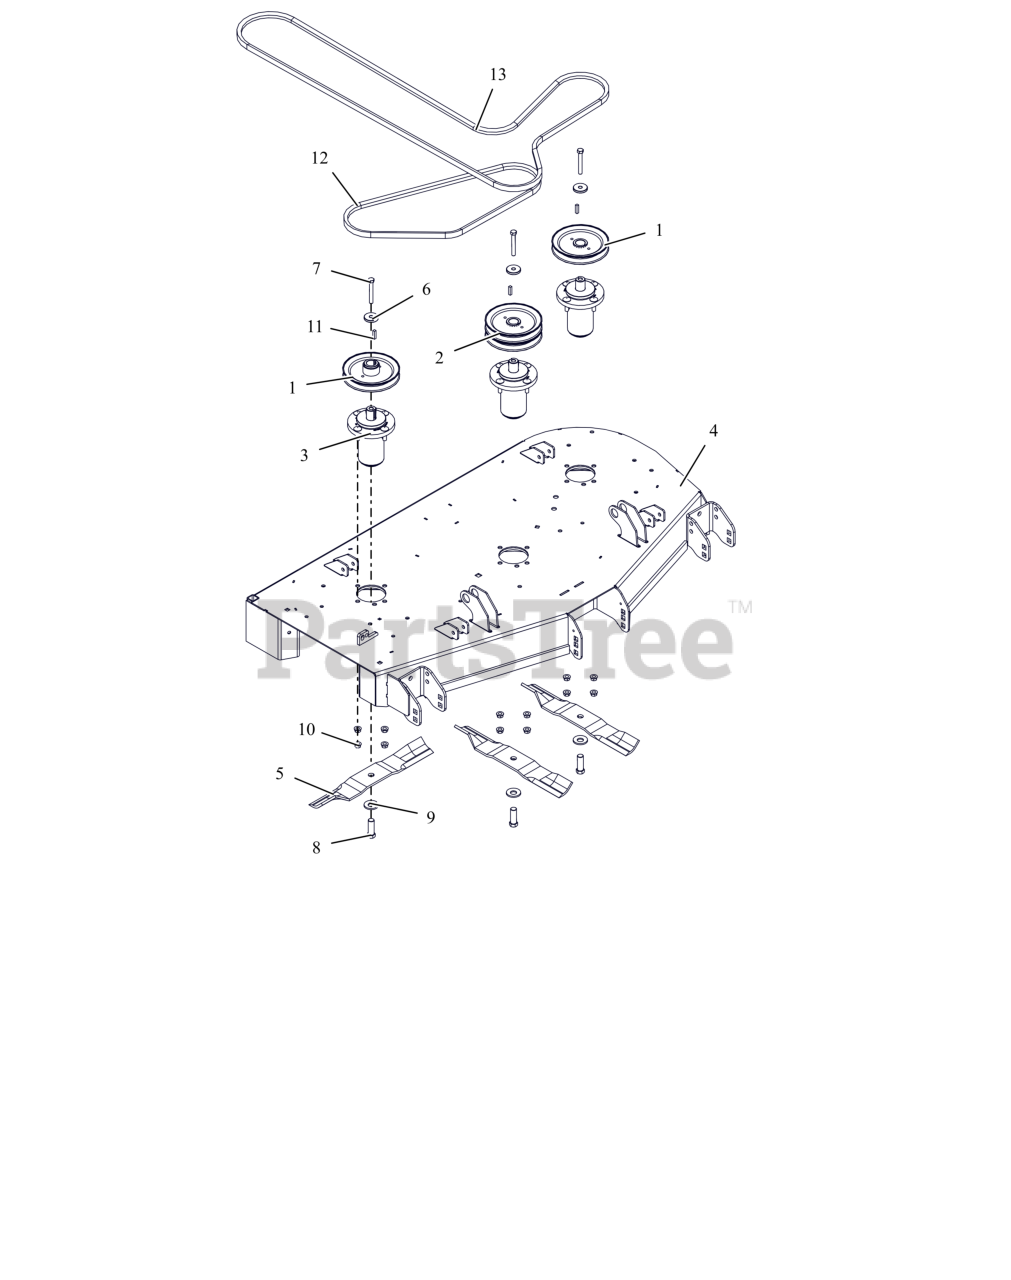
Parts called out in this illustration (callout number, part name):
1	PULLEY, SINGLE-1"ID X 6" OD
2	PULLEY, DOUBLE
3	ASM, MAINT FREE ALUM SPINDLE
4	KIT,DECK-48" W/DECALS-GRAVELY
5	BLADE, 16.19" MOWER (HI-LIFT)
6	RETAINER, SHEAVE
7	BLT, HEX .38-16X2.75 G8 ZCC
8	BLT, HEX .62-18X1.75 G8 ZCC
9	WSHR-BLVL .669X1.535X.138
10	NUT-LK-CTR-FLG .375-16 GF ZCC
11	KEY, SQ .25X.25X1.00 RC 40-50
12	V-BELT, B-COGGED
13	V-BELT, HB SECTION
